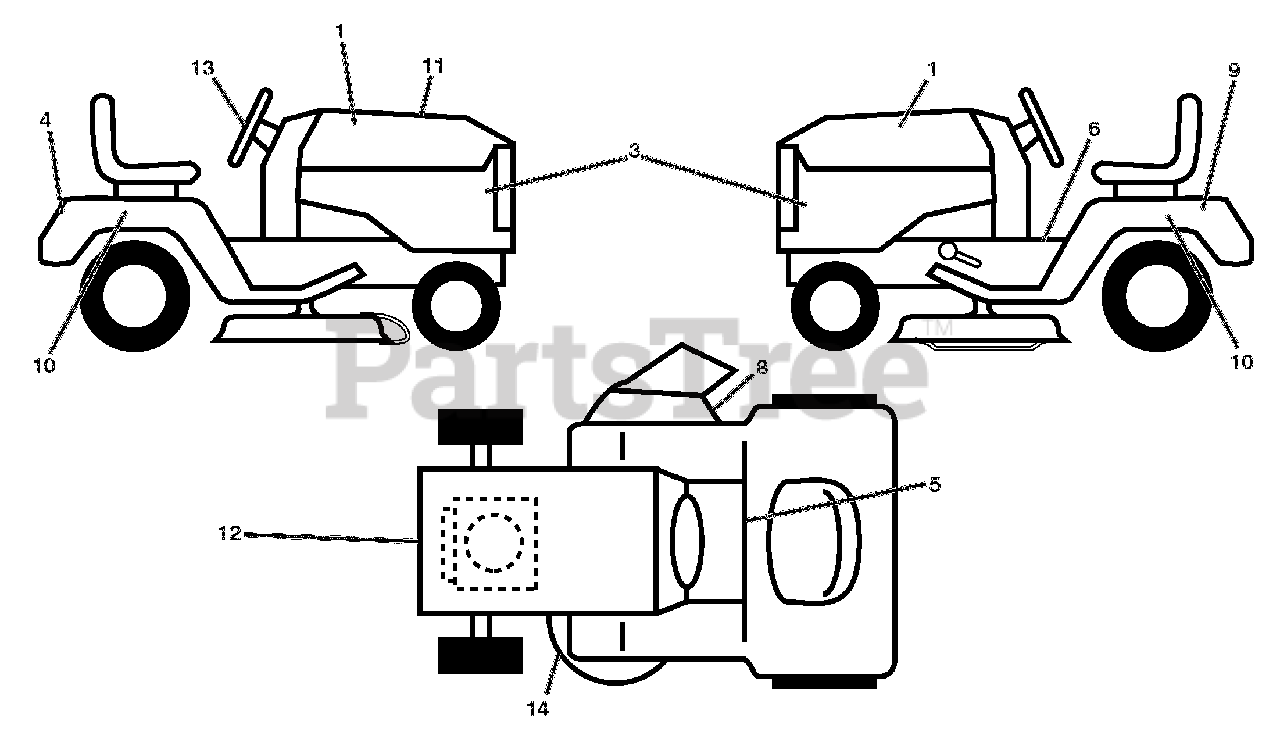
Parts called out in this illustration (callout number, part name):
1	DECAL.HOOD.RH.PRECISION.ARIENS
3	DECAL.SDPNL.PWRDBY KOHL.ARIENS
4	DECAL.FENDER.REAR.ARIENS
5	DECAL.FENDER
6	DECAL, WARNING START INST.
8	DECAL.MOWER.WARN.KEEP HAND AWY
9	DECAL.BAT.DAN/POI P/L SYM.WPN
10	DECAL.FENDER.SIDE.HYDRO.ARIENS
11	DECAL, REPLACEMENT
12	DECAL ENGINE
13	DECAL.WHEEL.STEER.ARIENS
14	DECAL.V-BELT.SCH.42/46"MEC/ELE
